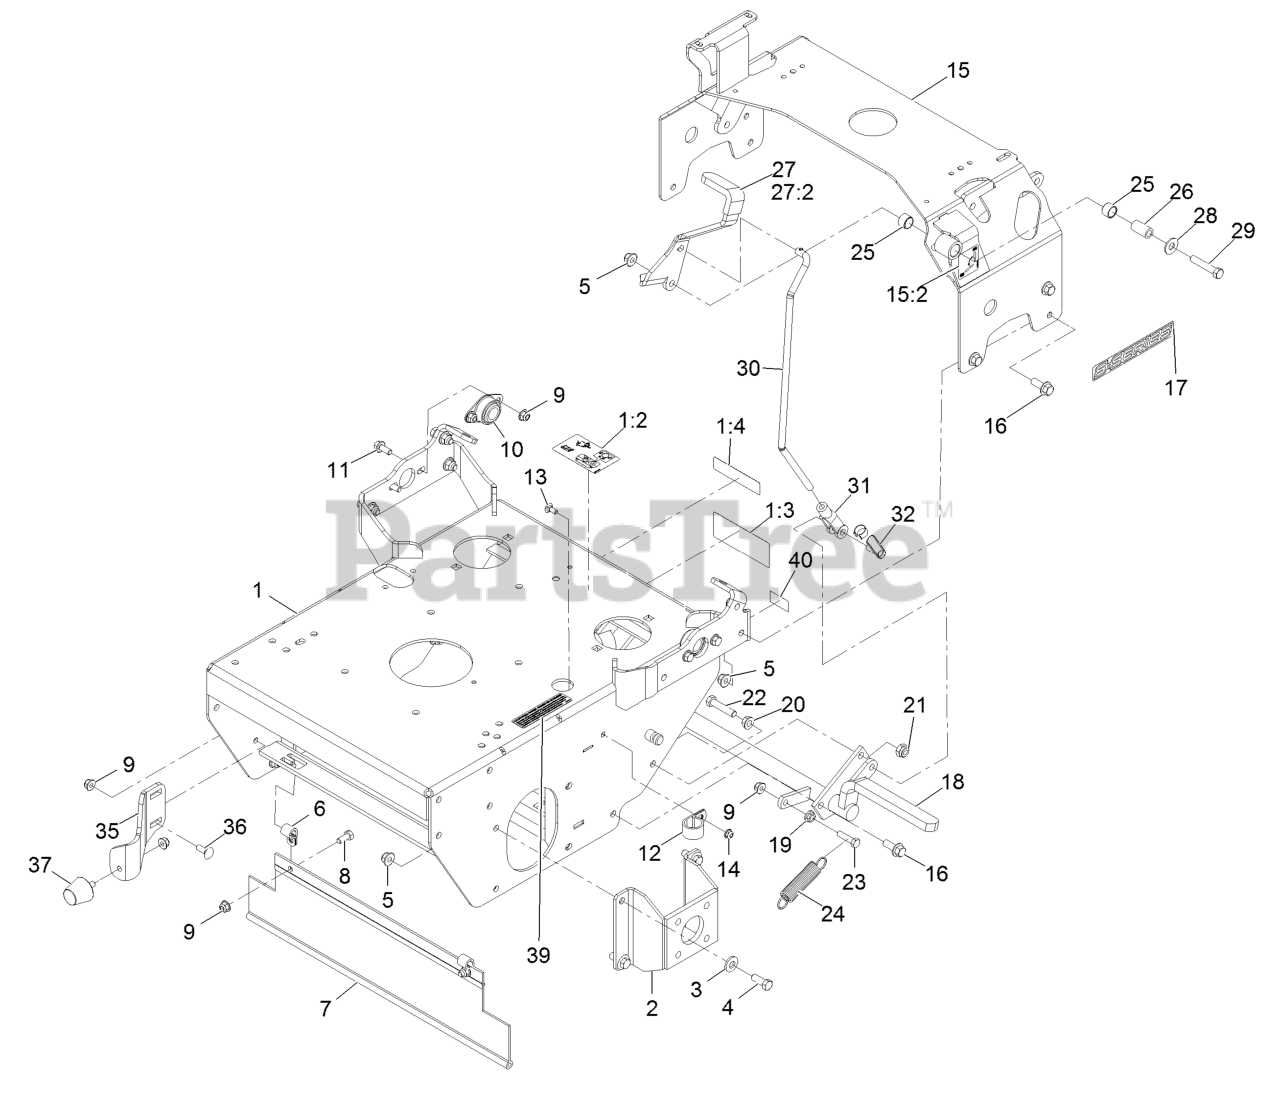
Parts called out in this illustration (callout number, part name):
1	ASM, ENGINE DECK W/ DECAL
1:2	DECAL-DRIVE RELEASE
1:3	DECAL-WARNING, SULKY
1:4	DECAL-WARNING
2	WLD,MOTOR MOUNT 36
3	WASHER-BELLEVILLE
4	SCREW-HH
5	NUT-HF, NI
6	CLIP-LOOM
7	SHIELD-DRAG
8	SCREW-HH
9	NUT-HF, NI
10	BEARING-FLANGE, SIDE
11	SCREW-HHF
12	CLIP-LOOM
13	SCREW-CARR
15	ASM, TANK SUPPORT W/ DECA
15:2	DECAL-PARK BRAKE, CE
16	SCREW-HHF 3/8-16 X 1
17	DECAL-S-SERIES
18	SHAFT-CROSS, BRAKE
20	NUT-HHF, WHIZ
21	NUT-LOCK, NI
22	SCREW-HH
23	SCREW-HH
24	SPRING-IDLER
25	SLEEVE-BUSHING
26	BUSHING-PIVOT
27	ASM, BRAKE LEVER W/ GRIP
27:2	GRIP-LEVER
28	WASHER-FLAT
29	SCREW-HH
30	LINKAGE, BRAKE
31	YOKE-LINKAGE, BRAKE
32	PIN-SPRING, CLEVIS
35	BRACKET-BUMPER
36	SCREW-CARR
37	BUMPER-RUBBER
39	DECAL-ARRESTER, SPARK
40	Decal-Patent Ttco.Com
